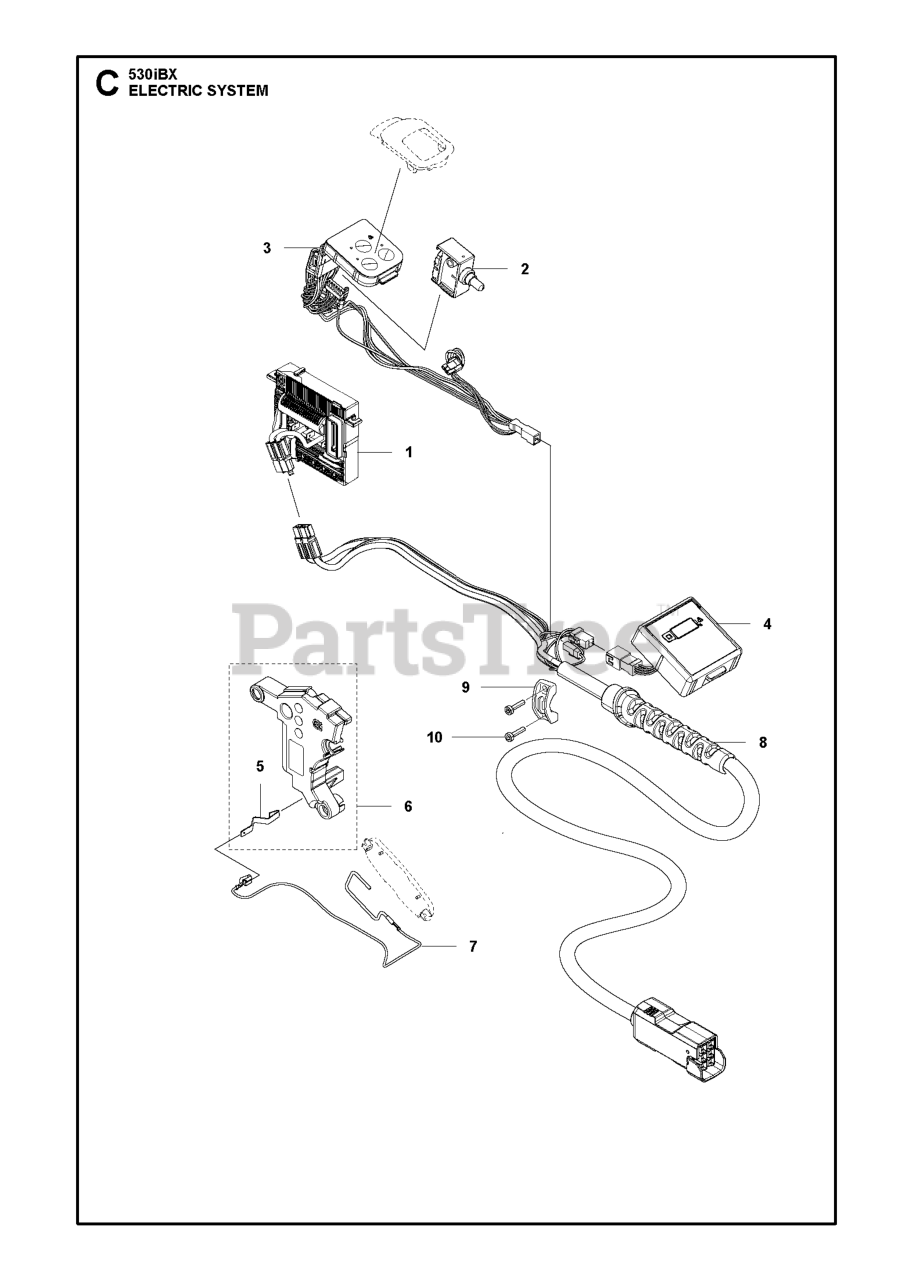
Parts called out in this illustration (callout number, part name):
1	CONTROL UNIT BLDC MID SPEC, GE
2	TRIGGER SWITCH IPX4
6	KIT COVER ELECTRONICS
7	WIRING ASSY
9	CABLE CLAMP
10	SCREW
